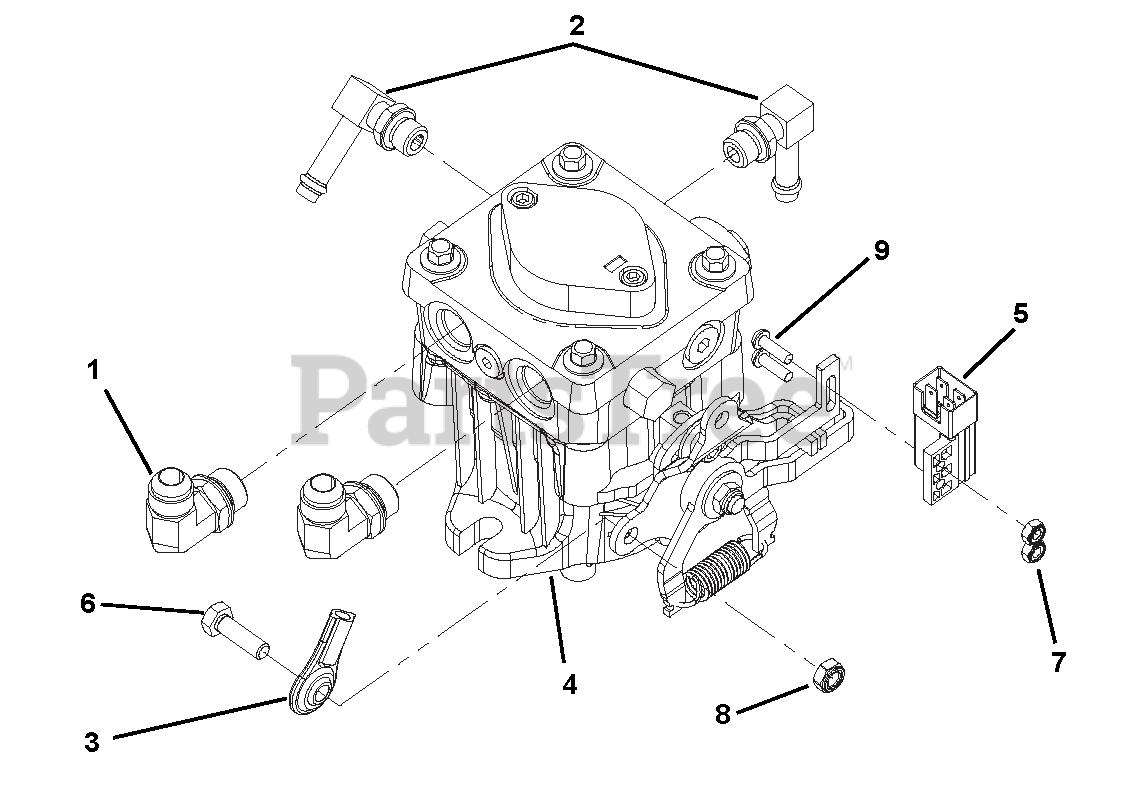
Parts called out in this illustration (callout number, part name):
1	FITTING, INCLUDES O-RING
2	FTG-ADPTR .562-18 ST THD
3	ALIGNABALL, 5/16 RH THREAD
4	PUMP, RH
5	SWITCH, PLUNGER DP -N.O.-N.C.
6	SPINDLE, STEERING FWD TOWER 70
7	@NUT-LK-NYL 10-24 W/INSRT YWZC
8	@NUT-LK-NYL .312-18 YWZC
9	SCR-MCH 10-24X.62 P/HD
